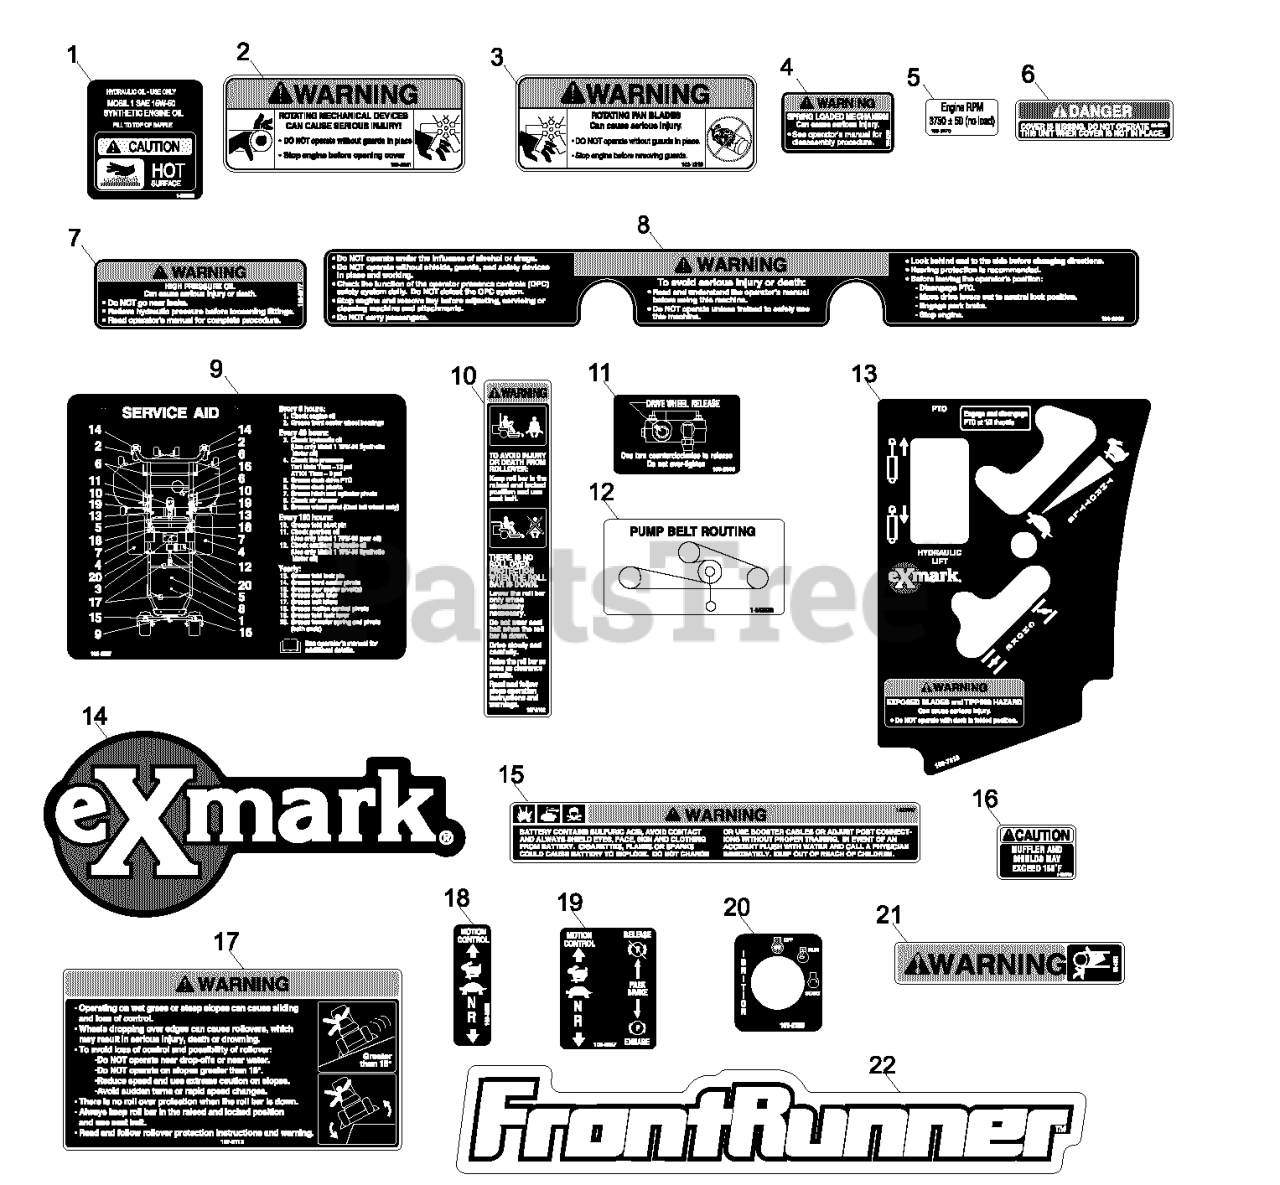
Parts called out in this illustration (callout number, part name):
2	DECAL-DEVICES, ROTATING
3	DECAL,PUMP FAN WARNING
4	DECAL,SPRING LOADED
6	DECAL-COVER, MISSING
7	DECAL,HIGH PRESSURE OIL
8	DECAL,TOP CONSOLE
9	DECAL,FR SERVICE AID
10	DECAL-WARNING, FOLDING RO
11	DECAL,PUMP DRIVE RELEASE
12	DECAL-ROUTING, BELT
13	DECAL,CONTROL FMZ A/C
14	DECAL,EXMARK LOGO
15	DECAL-BATTERY
17	DECAL-WARNING
18	DECAL-CONTROL, MOTION
19	DECAL,MOTION CNTL/PARK BR
20	DECAL,IGNITION
21	DECAL-WARNING
22	DECAL,FRONTRUNNER
22	KIT,DCL A/C FRTRNR TRACTO
